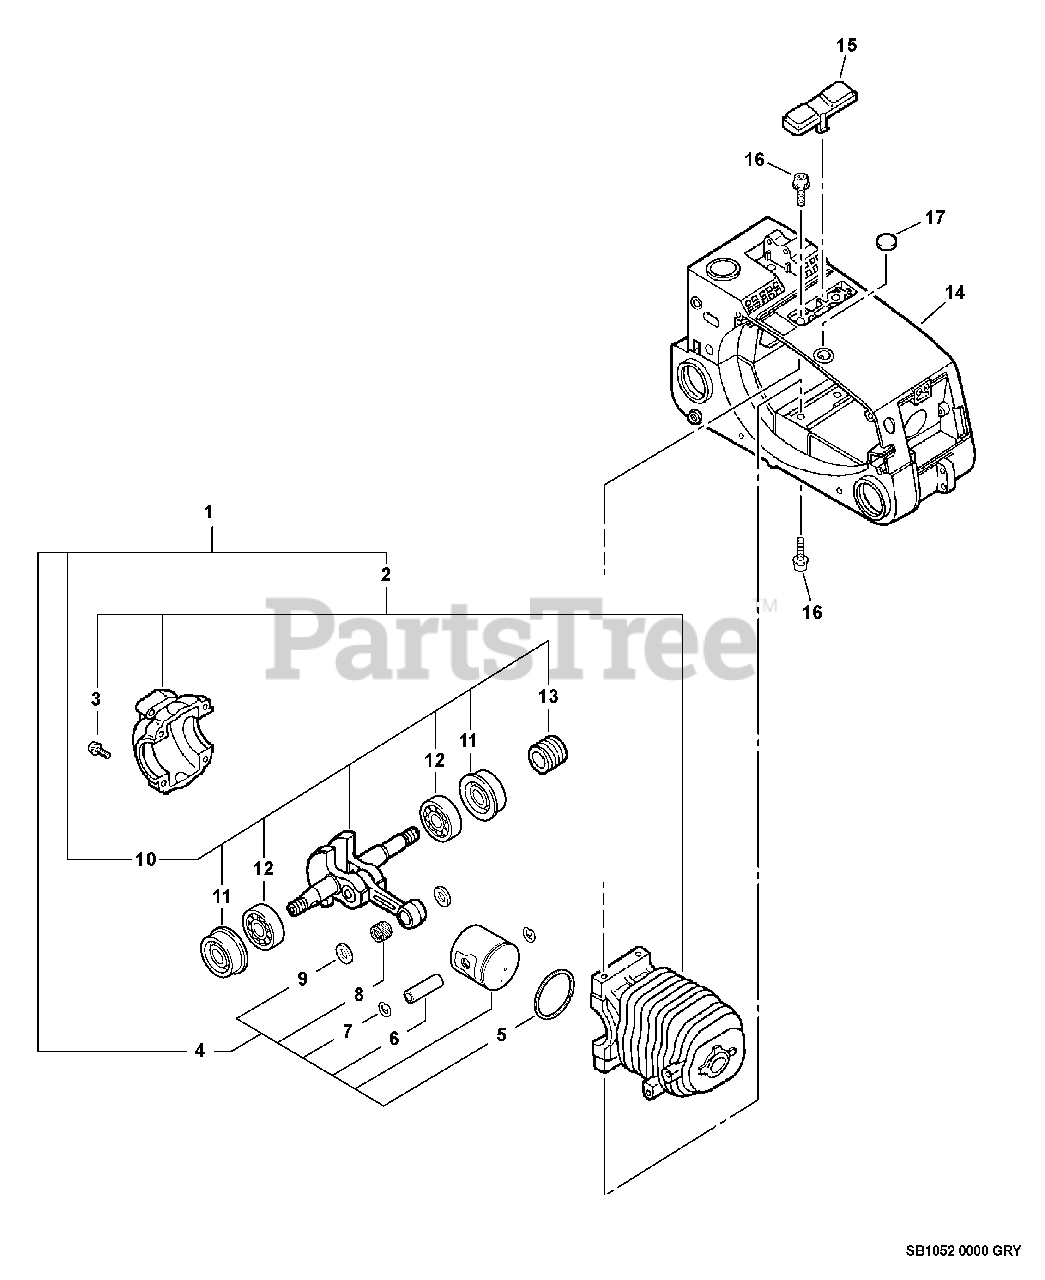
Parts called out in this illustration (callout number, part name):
1	SHORT BLOCK -- SB1052
2	CRANKCASE KIT
3	SCREW - 5X25
4	PISTON KIT
5	RING, PISTON
6	PIN, PISTON
7	RING, RETAINING
8	BEARING, NEEDLE
9	SPACER, PISTON
10	CRANKSHAFT ASSY
11	SEAL, OIL - 12
12	BEARING, BALL - 6201
13	GEAR - WORM
14	COVER, ENGINE - GRAY
15	COVER - GRAY
16	SCREW - 5X16
